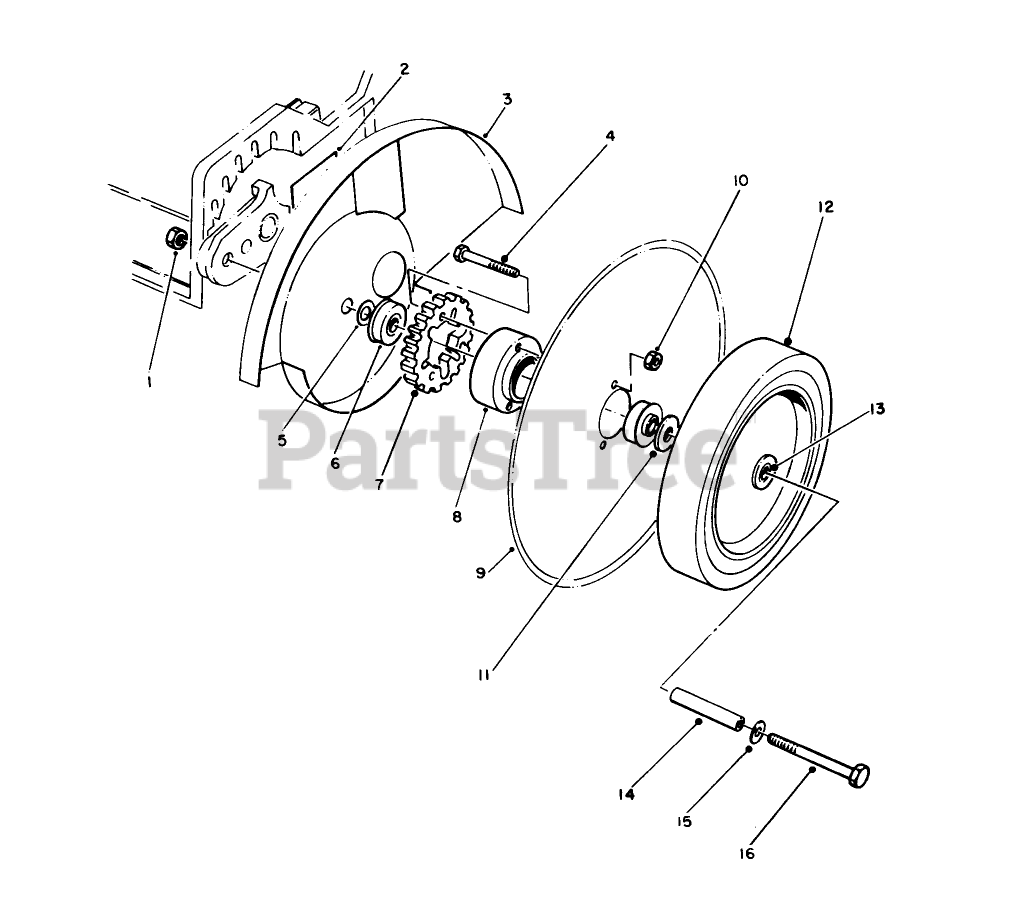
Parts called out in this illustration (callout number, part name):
4	SCREW-HH
5	WASHER
6	BEARING-BALL
10	NUT-LOCK, SIDE
11	WASHER
13	BUSHING
15	WASHER-FLAT
